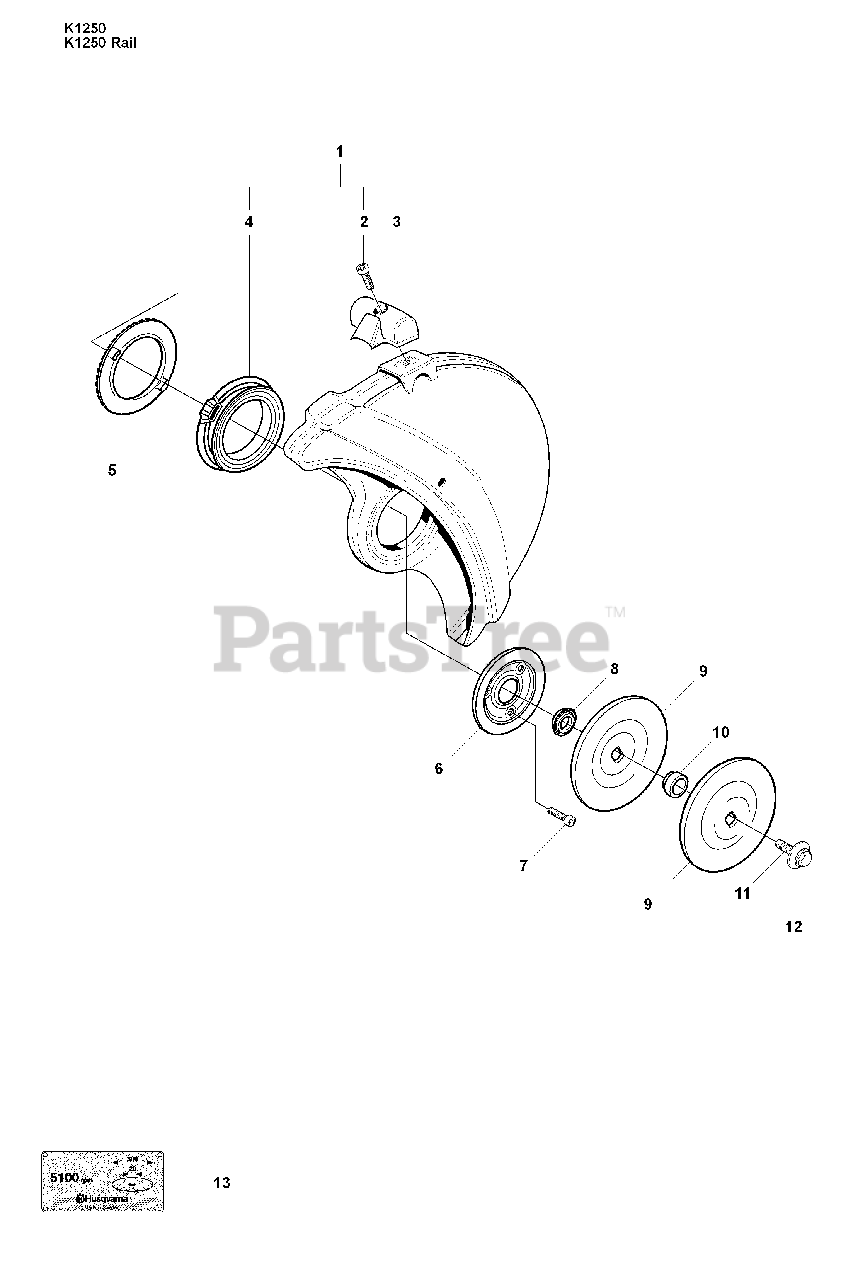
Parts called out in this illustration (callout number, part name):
1	WHEEL GUARD ASSY
2	SCREW
5	SCREEN PATTERN FLANG
8	SUPPORT FLANGE
9	FLANGE WASHER
9	WASHER
10	BUSHING
11	WASHER
12	COLLAR SCREW
13	LABEL
